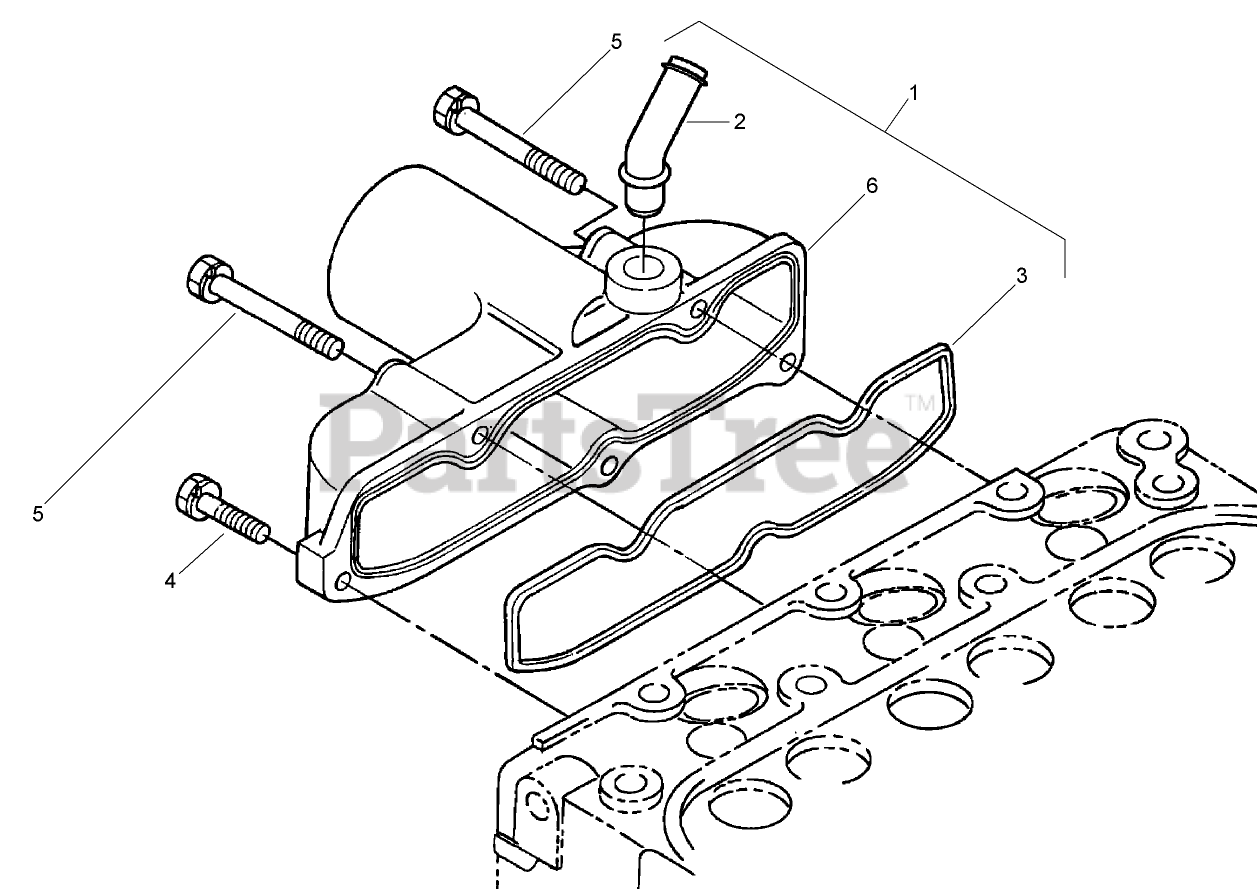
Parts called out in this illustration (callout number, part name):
1	INTAKE MANIFOLD ASM
2	PIPE-BREATHER
3	GASKET-MANIFOLD, INTAKE
6	MANIFOLD-INTAKE
